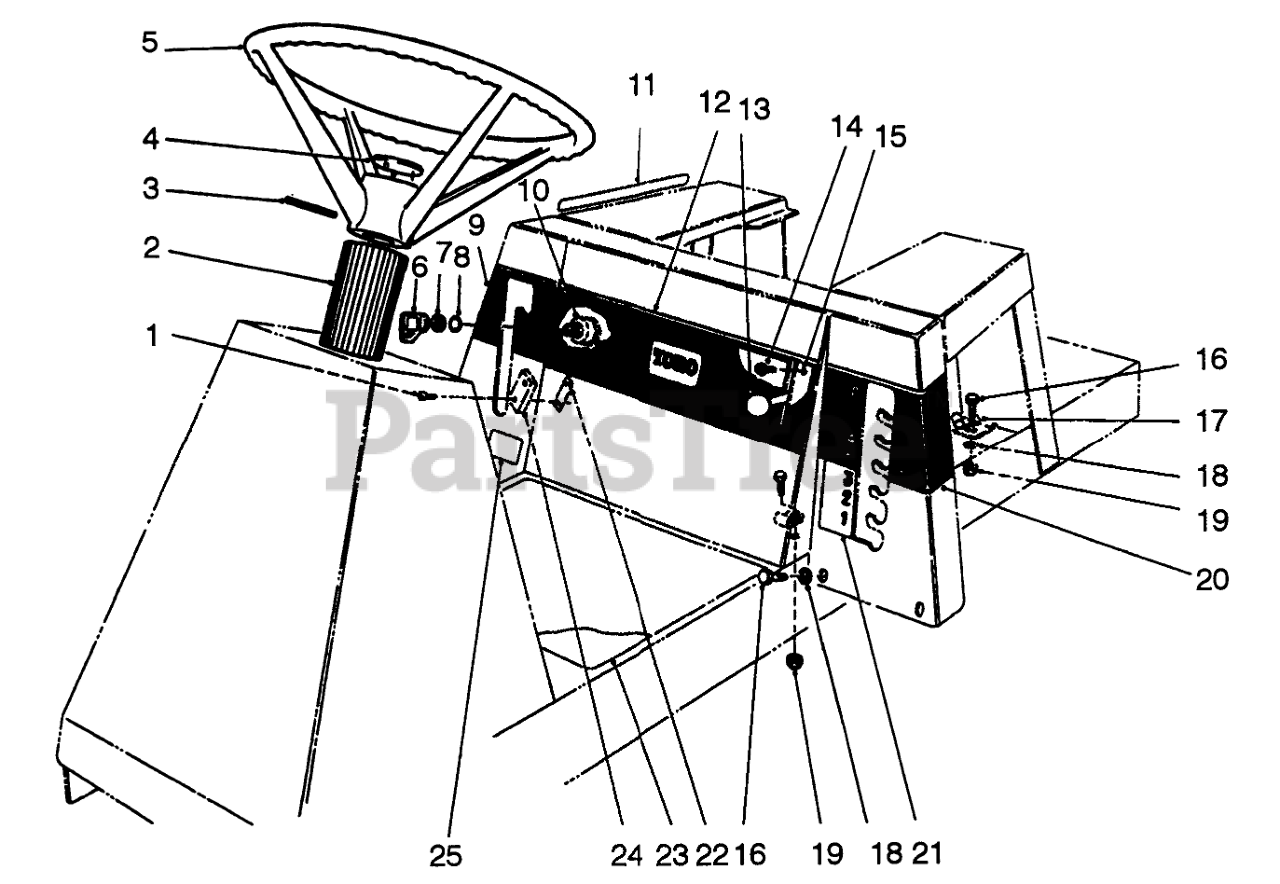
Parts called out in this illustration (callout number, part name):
1	SCREW-SPH
2	COVER-STEERING SHAFT
3	PIN-ROLL
4	STEERING WHEEL INSERT
5	Assy.-Wheel, Steering (Incl. Ref. #4)
6	KEY-IGNITION
7	NUT-HH
8	WASHER-TOOTH, INTERNAL
9	DECAL-UPPER DECK ENGAGE
10	Switch-Ignition (Incl. Ref. #6-8)
11	DECAL - SHIFT PATTERN
12	DECAL-FRT SEAT CONTROLS
13	KNOB-CONTROL
14	SCREW-HWHTF
15	Control-Throttle (Incl. Ref. #13)
16	SCREW-HH
17	CLAMP
18	WASHER-PLAIN
19	NUT-LOCK, NI
20	DECAL - UPPER HOC
21	DECAL - LOWER HOC
22	NUT-SPEED
23	INSTRUCTION DECAL
24	SWITCH-MICRO
25	DECAL-LOWER DECK ENGAGE
